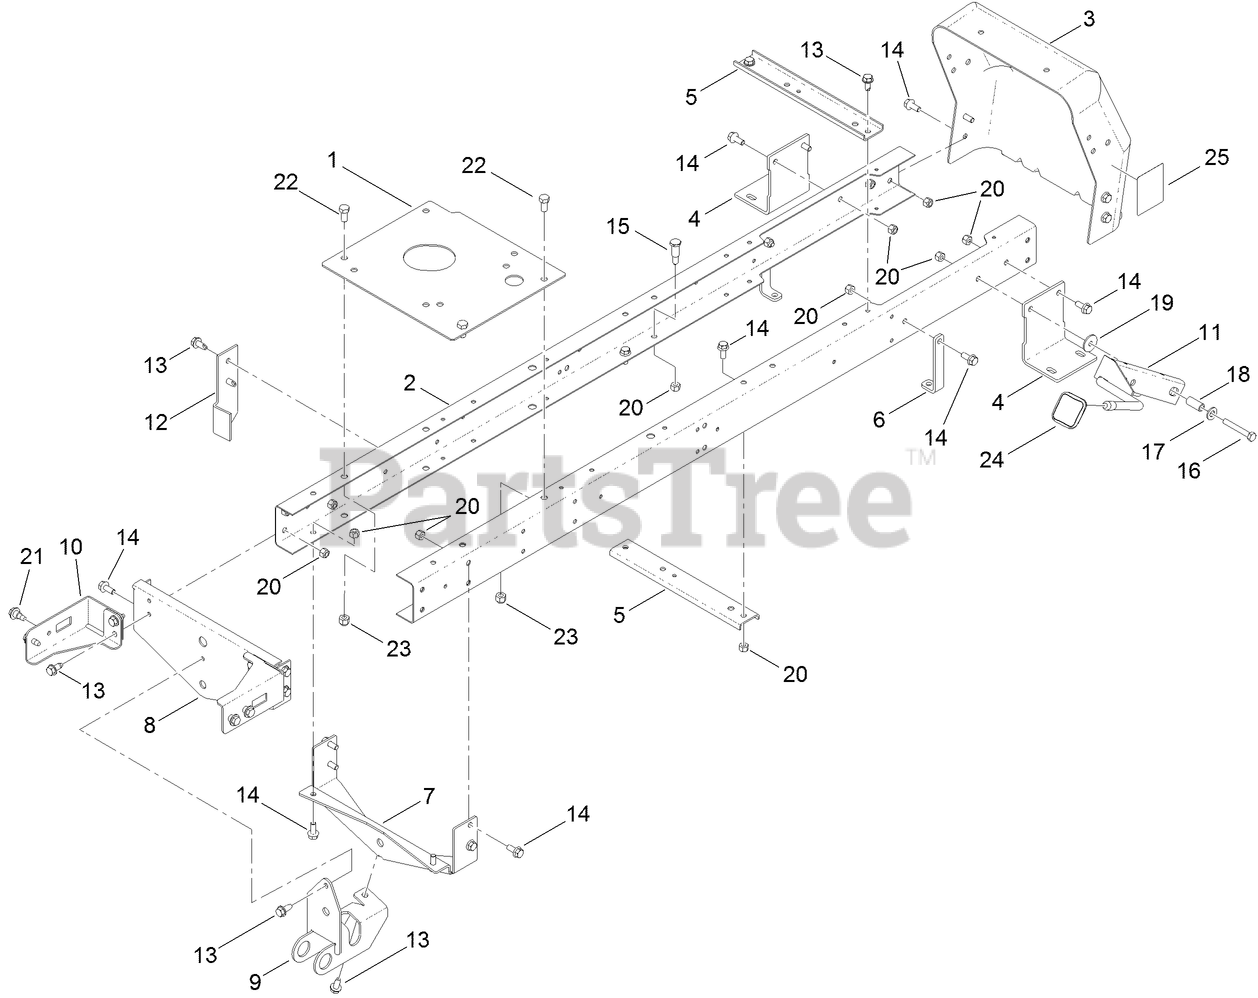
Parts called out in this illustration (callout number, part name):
1	PLATE-MOUNTING, ENGINE
2	RAIL-FRAME
3	SUPPORT-SEAT/REAR HITCH
4	AXLE-BRACKET
5	BRACE-IDLER
6	STRAP-TORQUE
7	SUPPORT-AXLE, FRONT REAR
8	SUPPORT-AXLE, FRONT
9	BRACKET-PIVOT, DECK
10	BRACKET-HOOD
11	LEVER-HOC
12	STOP-CLUTCH
13	SCREW-HWH
14	SCREW-HHF
15	SCREW-SHOULDER
16	SCREW-HH
17	WASHER-FLAT
18	SPACER
19	WASHER-PIVOT
20	NUT-HF, NI
21	BOLT-SHOULDER
22	SCREW-HH
23	NUT-LOCK, NI
24	KNOB-SHIFT
25	DECAL-VALVE, DUMP
